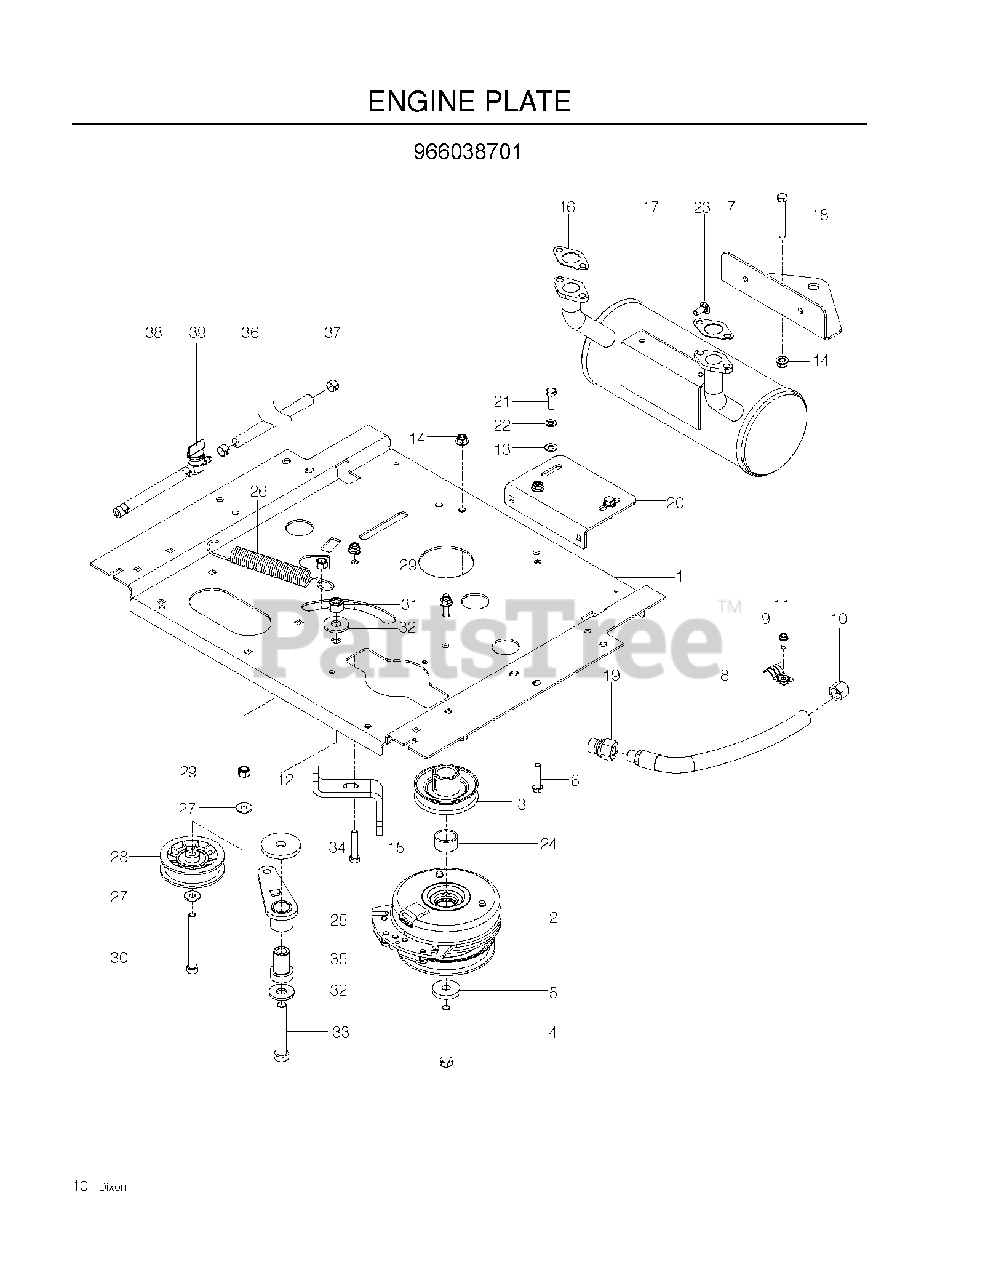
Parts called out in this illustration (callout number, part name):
1	PLATE, ENGINE, BLACK
2	CLUTCH, 105 FT-LBS
3	PULLEY, ENGINE
4	HCS 7/16-20X3-1/2 GR 5 ZN
5	CLUTCH, WASHER
6	CAPSCREW 5/16 X 1/1/2 HEX HEAD
7	HITCH, BLACK
8	OIL DRAIN HOSE
10	DRAIN CAP
11	SCREW 1/4 X 5/8
12	STOP, CLUTCH BLK
13	FLAT WASHER 5/16 SAE
14	5/16-18 NYLOC FLANGE NUT
15	HCS 5/16C X 1 3/4
16	EXHAUST GASKET - KAW
17	MUFFLER KAWASAKI GEN II
18	BOLT 5/16C X 2 1/2
19	ADAPTER, OIL DRAIN
20	BRACKET MUFFLER, BLK
21	HCS 5/16C X 1
22	WASHER 5/16 LOCK
23	BOLT 5/16C X 3/4" CARRIAGE
24	T & B SPACER
25	IDLER ARM WELDMENT
26	SPRING, DECK DRIVE
27	WASHER 5/16 FLAT
28	PULLEY, IDLER
29	NUT 3/8-16 NYLOC
30	HCS 3/8-16X3 1/2 GR5
31	NUT 1/2-13 HEX NYLOC ZD
32	WASH USS FLAT 1/2
33	HCS 1/2C X 3 1/4
34	HEAVY WASHER
35	IDLER SPINDLE
37	HOSE CLAMP
38	HOSE 1/4 X 8
39	FUEL VALVE
